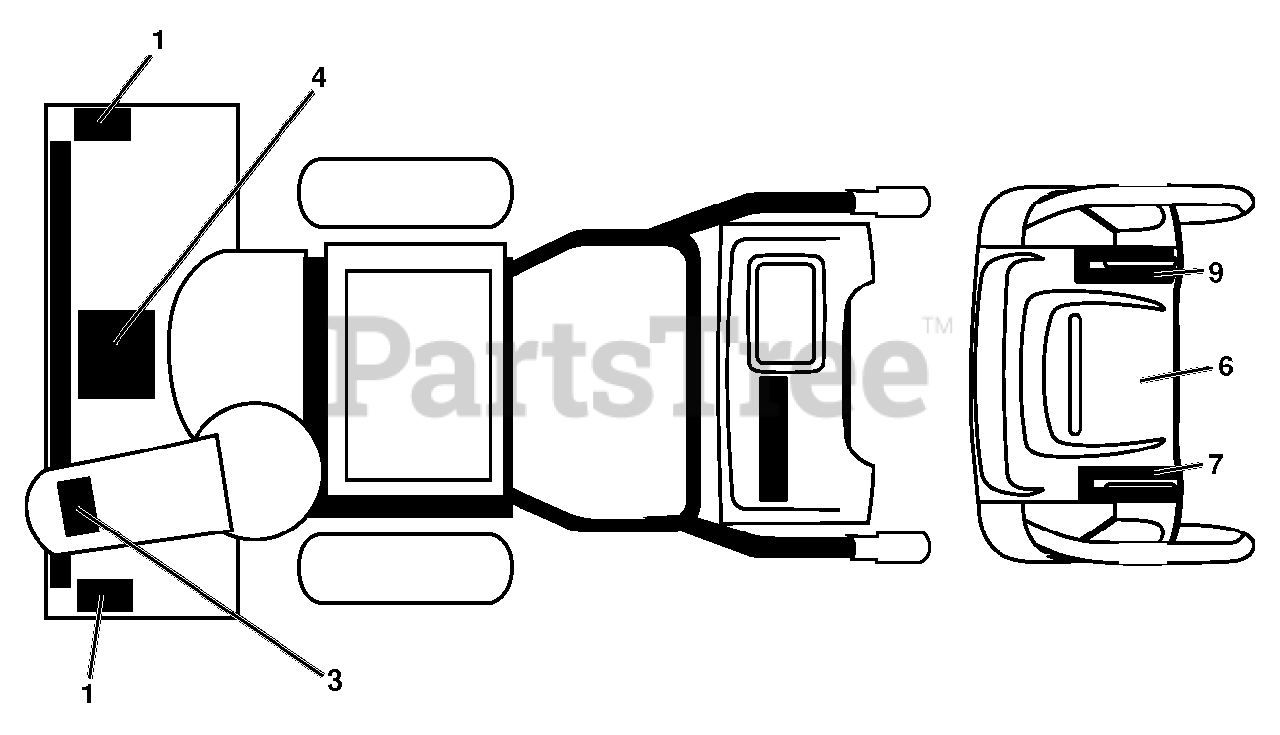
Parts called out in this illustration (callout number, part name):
1	DECAL.SNOWTHR.AUGER
3	DECAL.SNOWTHR.CHUTE.SAFETY
4	DECAL.SNOWTR.READ.OWN.MAN.E/F
6	DECAL.CONSOLE.SNOW.INST.ENG/FR
7	DECAL.CONS.LH.REMOTE.INST.GRY
9	DECAL.CONS.RH.INST.GRY
